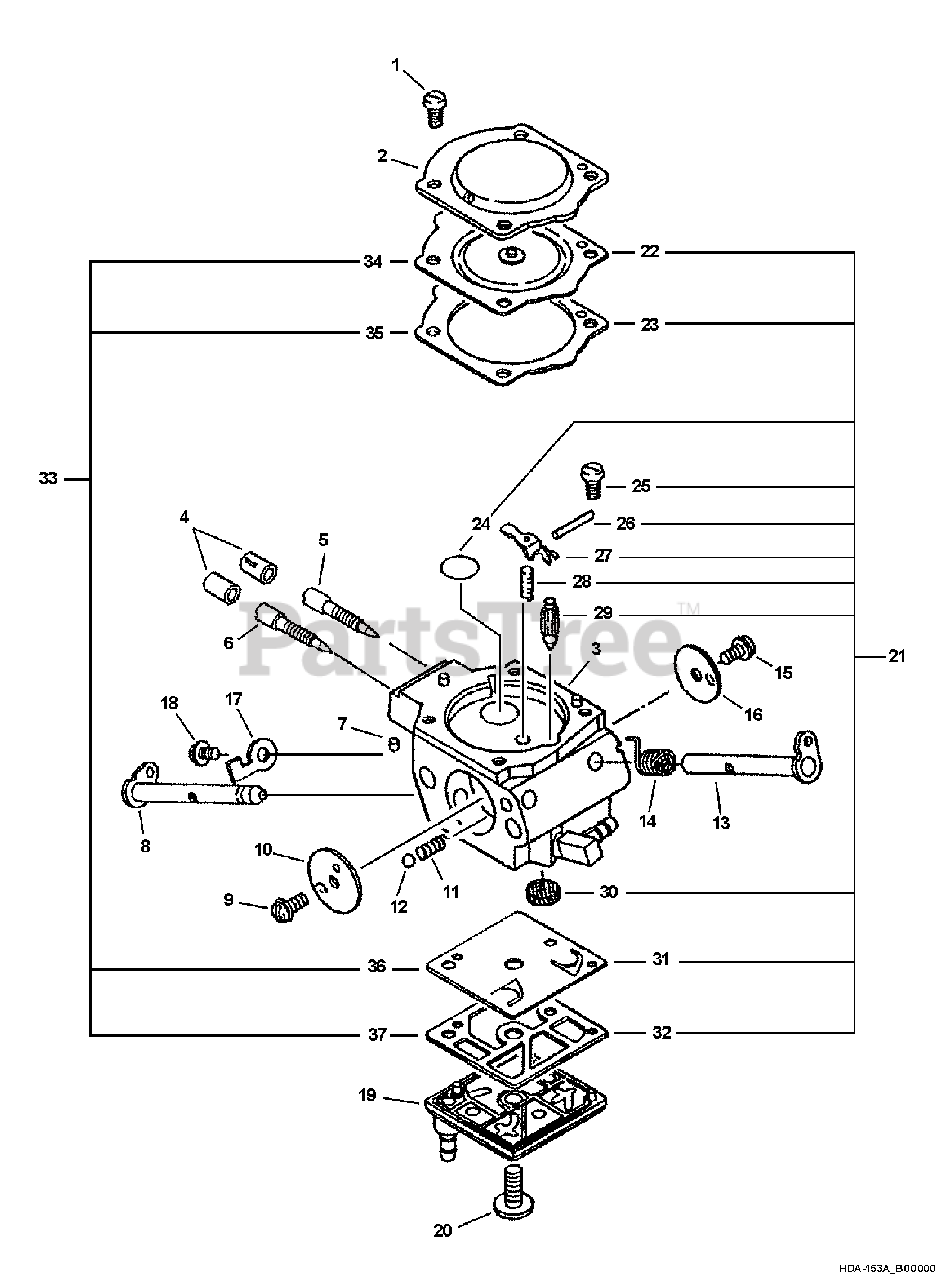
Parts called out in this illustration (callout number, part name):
1	SCREW
2	COVER, METERING
3	BODY, CARBURETOR
4	CAP, LIMITER
5	NEEDLE - LOW SPEED
6	NEEDLE - HIGH SPEED
8	SHAFT, CHOKE
10	VALVE, CHOKE
12	BALL, CHOKE
13	SHAFT, THROTTLE
14	SPRING, THROTTLE RETURN
16	VALVE, THROTTLE
17	STOP, THROTTLE
19	COVER, PUMP
20	SCREW, PUMP COVER
21	REPAIR KIT
22	DIAPHRAGM, METERING
23	GASKET, DIAPHRAGM
24	PLUG, WELCH
25	SCREW, METERING LEVER PIN
26	PIN, METERING LEVER
27	LEVER, METERING
28	SPRING, METERING LEVER
29	VALVE, INLET NEEDLE
30	STRAINER
31	DIAPHRAGM, PUMP
32	GASKET, PUMP
33	DIAPHRAGM/GASKET KIT
34	GASKET, DIAPHRAGM
35	DIAPHRAGM, METERING
36	DIAPHRAGM, PUMP
37	GASKET, PUMP
